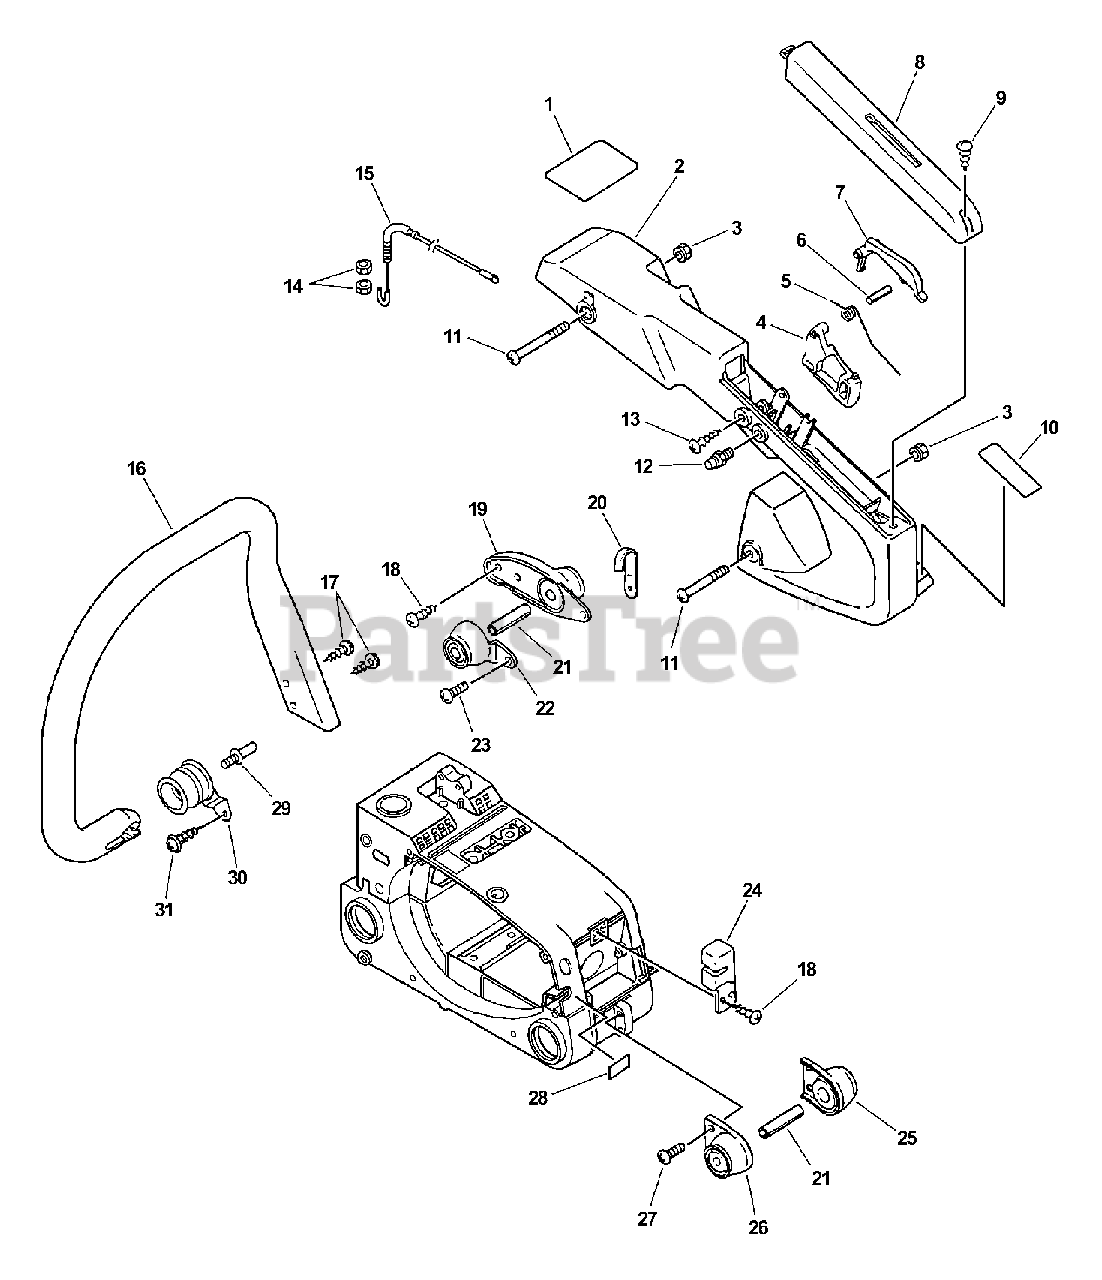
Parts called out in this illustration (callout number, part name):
1	LABEL, UL - KICK BACK
2	HANDLE, REAR
3	NUT, FLANGE M5
4	CONTROL, THROTTLE
5	SPRING, THROTTLE LOCKOUT
6	ROLLER, 4×19.8
7	LOCKOUT, THROTTLE
8	COVER, HANDLE
9	SCREW 4×22
10	LABEL - CAUTION
11	SCREW 5×57
12	LOCK, THROTTLE TRIGGER
13	SCREW 4×25
15	CABLE, THROTTLE
16	HANDLE, FRONT
17	SCREW, TAPPING 5×20
18	SCREW 4×14
19	CUSHION
21	COLLAR 5
23	SCREW 4×10
27	SCREW 4×14
28	LABEL, STOP
30	CUSHION 5
31	SCREW 4×16
